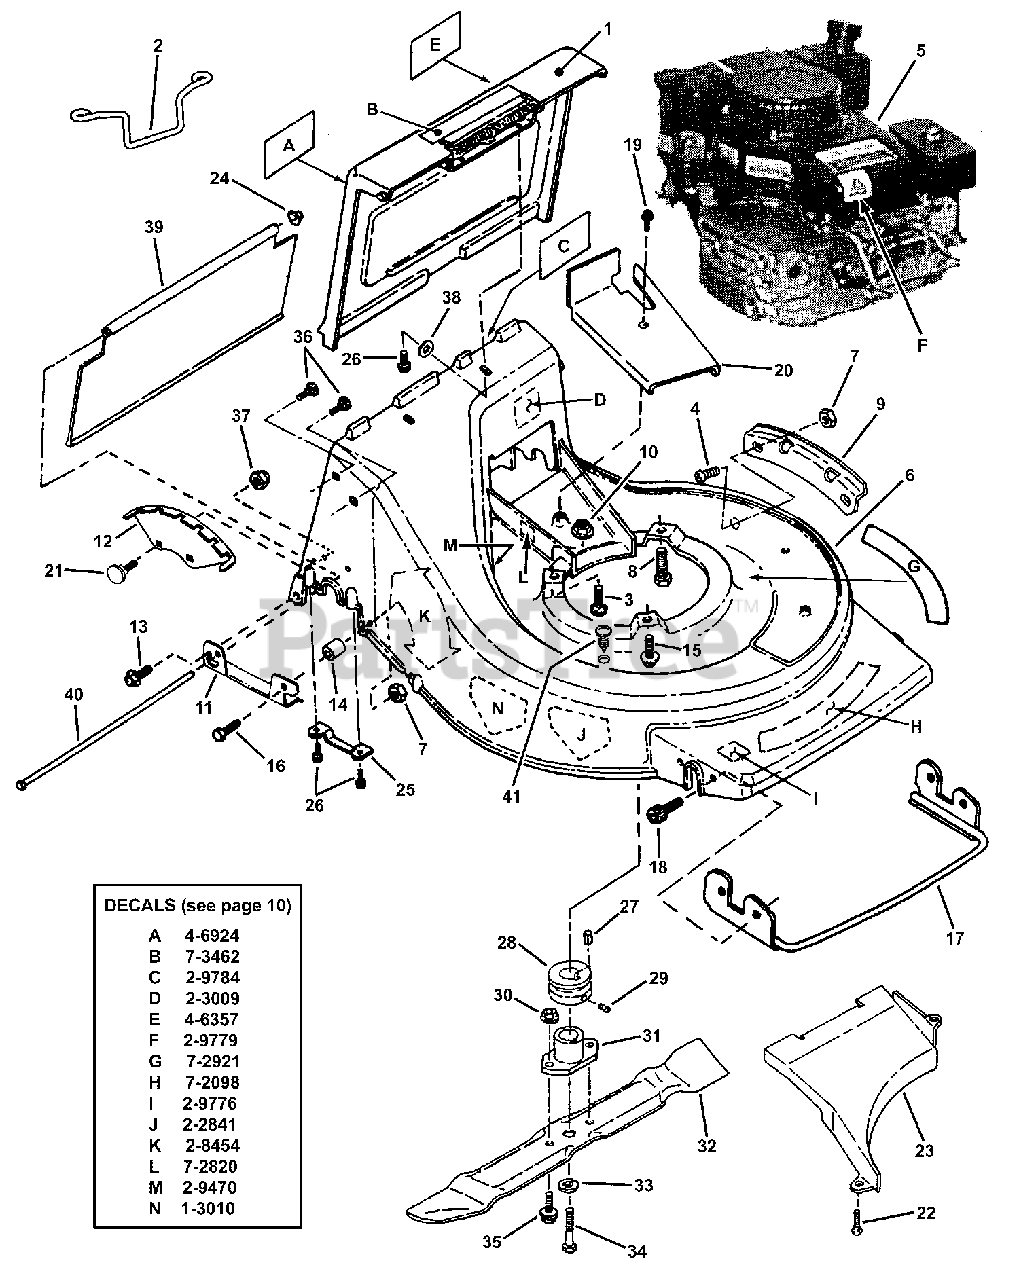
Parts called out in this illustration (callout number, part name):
1	ASSEMBLY, Discharge Door (Commercial)
2	GUIDE, Belt
3	BOLT, 5/16-18 x 1-1/2" Hex Flange Lock GR5
4	SCREW, 1/4-20 x 5/8" Phillips Truss Head Machine
6	DECK, 21" Cast Aluminum Short (Red)
7	NUT, 1/4-20 Hex Nyloc
8	SCREW, 3/8-16 x 1" Hex Washer Face Self-Tap
9	GUARD, Wear
10	NUT, 5/16-18 Hex Flange Lock GR5
11	BRACKET, R.H. Stiffener w/tab
12	PLATE, Height Adjust
13	SCREW, 1/4-20 x 5/8" Hex Washer Face Self-Tap
14	SPACER, Stiffener
15	BOLT, 5/16-18 x 3/4" Hex Flange Lock GR5
16	SCREW, 1/4-20 x 1" Hex Head Cap GR5
17	WELDMENT, Front Bumper
18	SCREW, 1/4-20 x 5/8" Truss Head (Torx)
19	SCREW, #10-24 x 1-1/2" Slotted Hex Washer Head Self-Tap
20	COVER, Ground Speed Drive Belt
21	BOLT, #10-24 x 5/8" Flat Head Carriage
22	SCREW, #10-24 x 5/8" Slotted Hex Washer Head Self-Tap
23	WELDMENT, Baffle
24	PUSHNUT, 1/4 Black
25	SUPPORT, Rear Axle
26	SCREW, 1/4-20 x 5/8" Hex Washer Face Self-Tap
27	KEY, 1/4" Square x 3/4"
28	PULLEY, Traction Drive
29	SCREW, 5/16-18 x 5/16" Hex Socket Head
30	NUT, 3/8-16 Hex Nyloc
31	HUB, Blade Drive, 25mm Internal Dia.
32	BLADE, 21" Bagging
33	WASHER, 3/8" Split Lock (Heavy)
34	SCREW, 3/8-24 x 1-3/4" Hex Head Cap GR5
35	BOLT, 3/8-16 x 1-1/4" Hex Flange Lock
36	BOLT, 5/16-18 x 1" Round Head Carriage GR5
37	NUT, #10-24 Hex Center Lock
38	WASHER, 1/4" Flat
39	SHIELD, Trailing, Commercial Cast
40	ROD, Trailing Shield Pivot (1/4" Dia.)
41	PLUG, Hole (Polyethylene)
